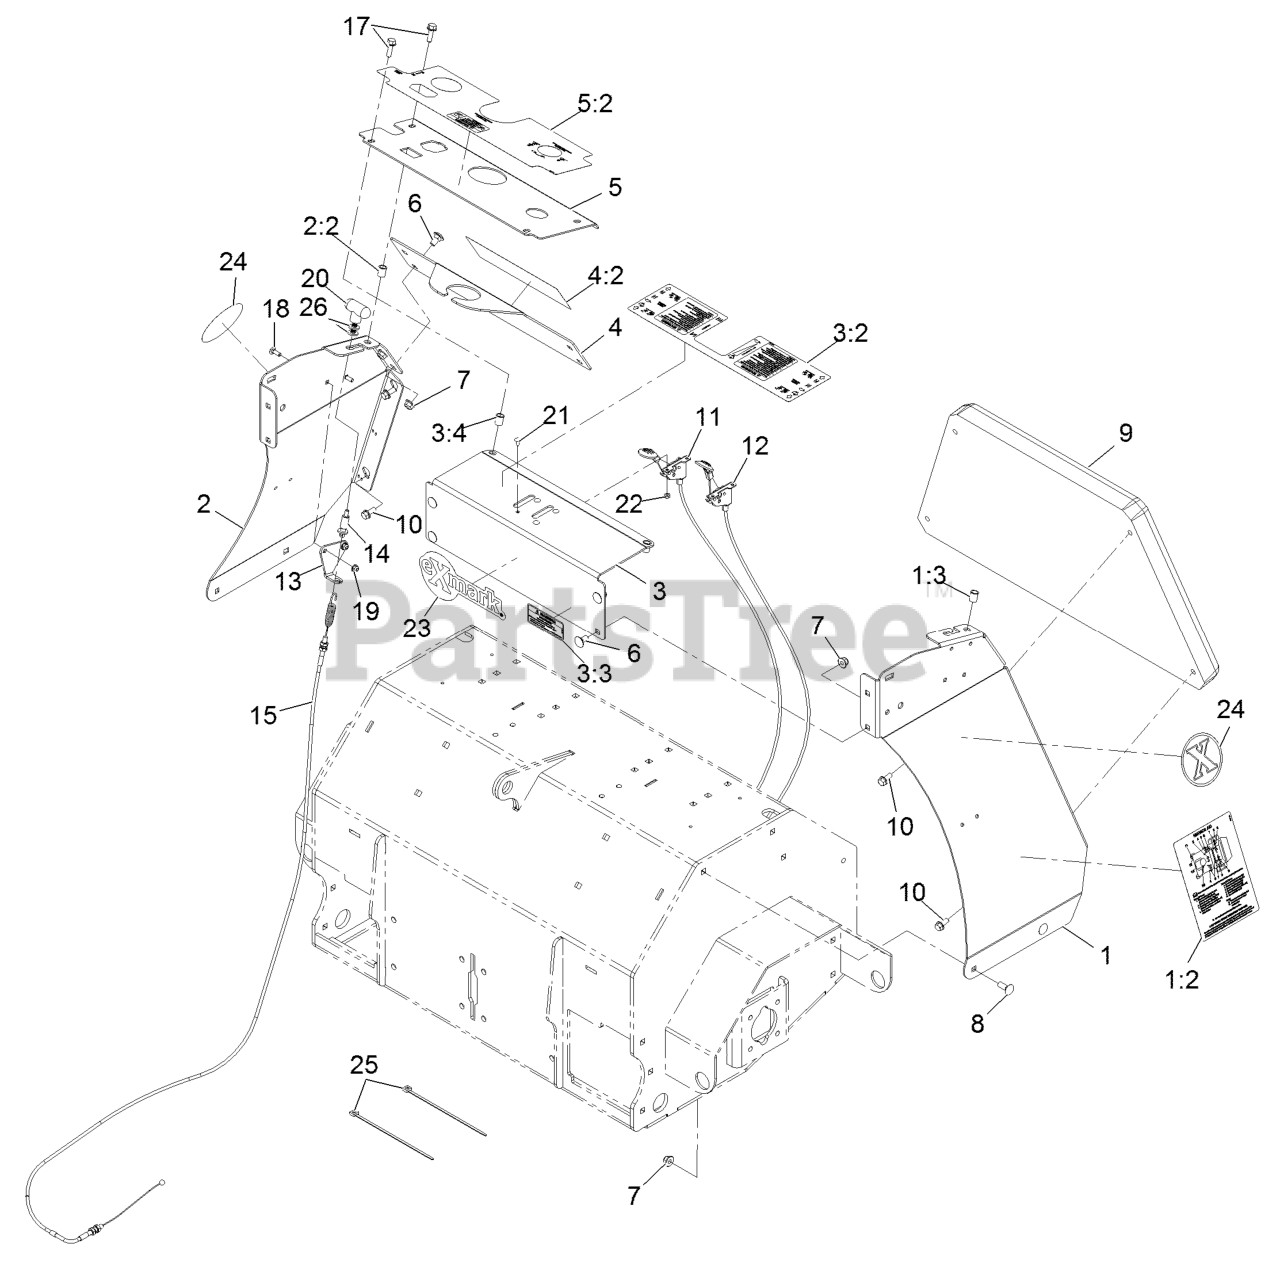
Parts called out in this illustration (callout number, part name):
1	PANEL-SIDE, LH W/DECALS -
1:2	DECAL-SERVICE AID
1:3	NUT-CLINCH
2	ASM-PANEL,SIDE RH (BLACK)
2:2	NUT-CLINCH
3	ASM-PLATE W/DECAL
3:2	DECAL-CONTROL PANEL WARNI
3:3	DECAL-WARNING STORED ENER
3:4	NUT-CLINCH
4	BRACKET-KNEE PAD W/ DECAL
4:2	DECAL-SLOPE WARNING
5	ASM-CONSOLE W/DECAL
5:2	DECAL-CONTROL PANEL DANGE
6	SCREW-HH
7	NUT-HF, NI
8	BOLT-CARR
9	CUSHION, GREY
10	SCREW-HHF
11	CONTROL-CHOKE
12	CONTROL-THROTTLE
13	BRACKET-CABLE, BRAKE
14	LINK-CABLE, BRAKE
15	CABLE-BRAKE
17	SCREW-HHF
18	BOLT-CARR
20	KNOB-TEE
21	BOLT-CARR
22	NUT-LOCK, NI
23	DECAL,EXMARK LOGO
24	DECAL-EXMARK X-LOGO 3.85
25	TIE-PLASTIC
26	WASHER-FLAT
